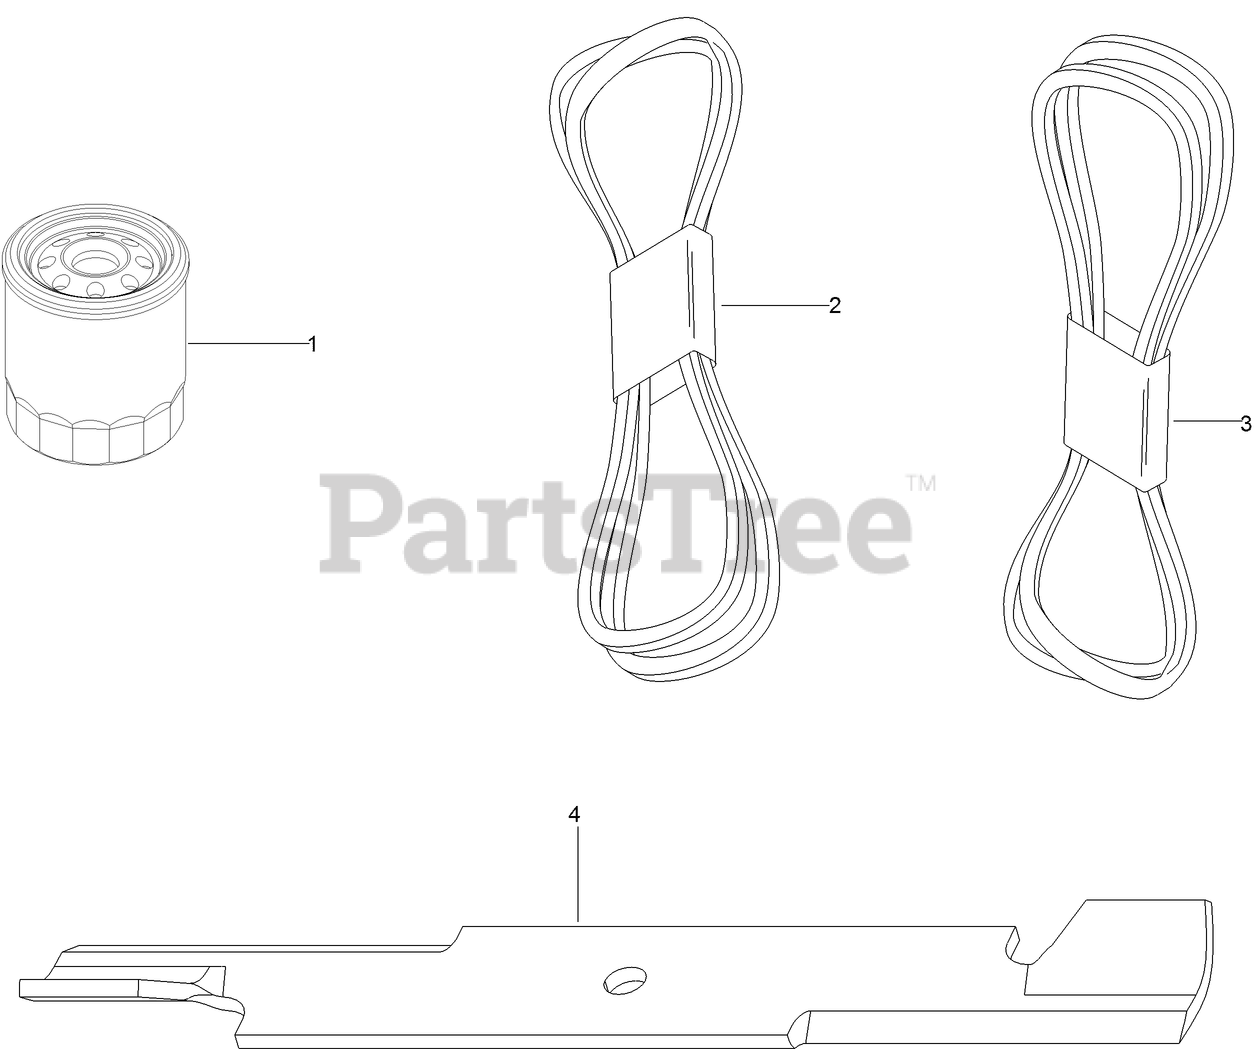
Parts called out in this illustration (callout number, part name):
1	ELEMENT-OIL FILTER, HYD
2	BELT-V
3	BELT-V
4	BLADE-HI FLOW, 18 IN
